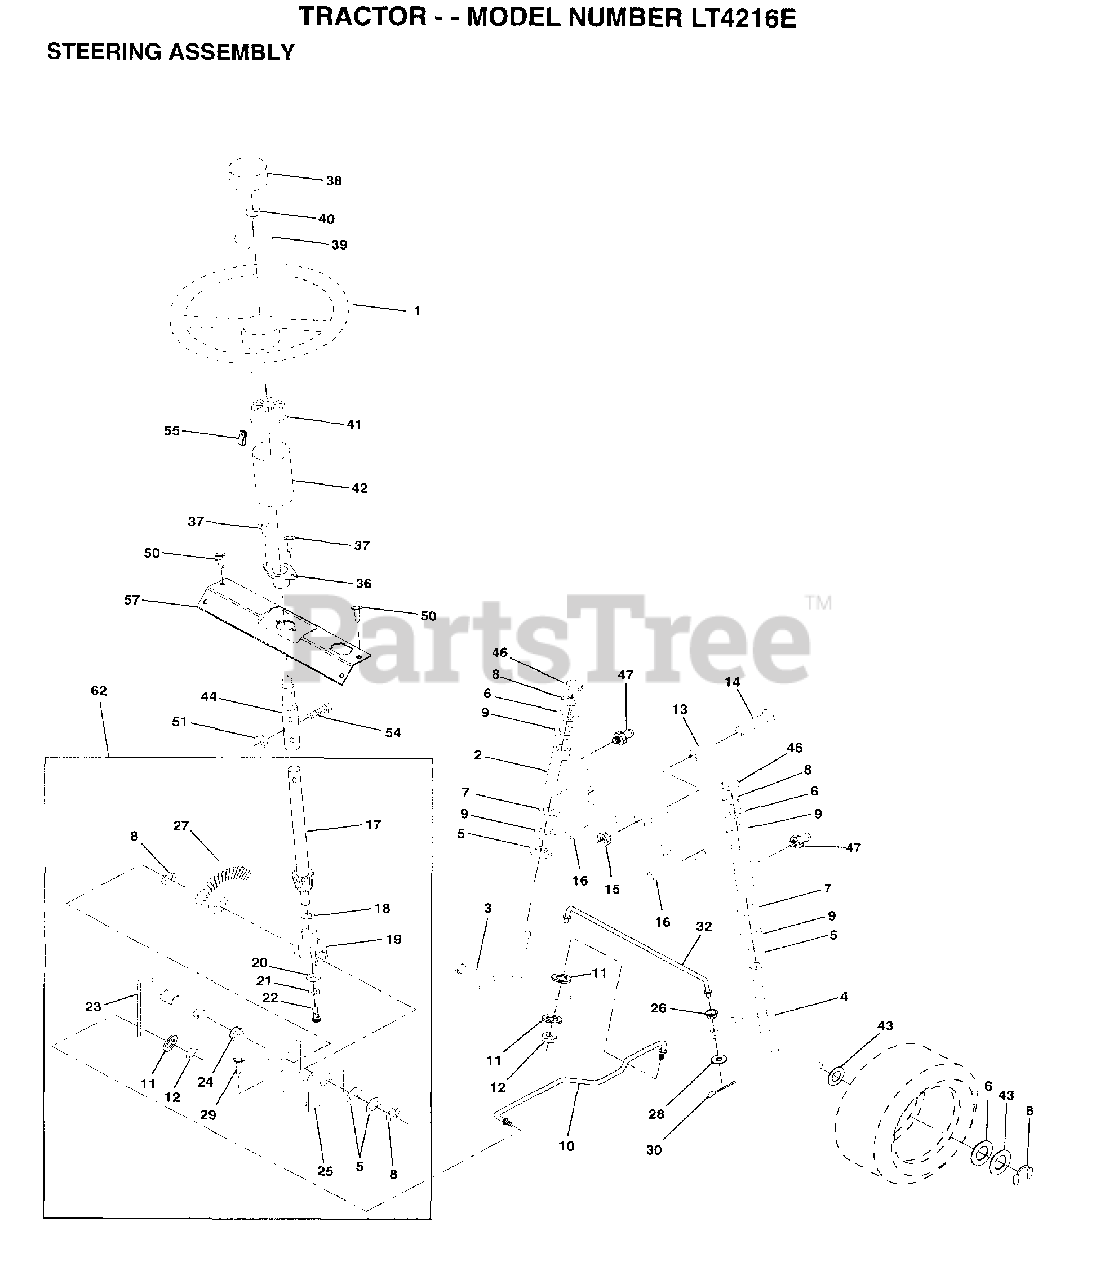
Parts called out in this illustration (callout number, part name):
1	WHEEL STR AYP BLK
2	AXLE ASM FRONT
3	SPINDLE LH
4	SPINDLE RH
5	WASHER .T
6	WASHER
7	WASHER
8	RING
9	COL. SRTG. BEAR.
11	LOCKWASHER
13	BEARING
14	BOLT HEX 5/8-11
15	"NUT-LOC,FLANGE LT"
16	AXLE PIN
17	SHAFT ASM STEERIN
18	THRUST WASHER
19	SUPPORT.SHAFT
21	LOCKWASHER
22	SCREW.SCKTHD.CAP
24	NYLINER T
25	"BRKT,STEERING"
26	BUSHING.DRAGLINK
27	GEAR SECTOR
28	WASHER
29	SCREW
30	COTTER PIN
32	TIE ROD
38	CAP STEER AYP
39	WASHER T
40	GRIPCO NUT
41	ADAPTER-WHEEL LT
42	BOOT SHAFT STEER
43	WASHER
46	CAP
47	ZERK M
50	SCREW HEX CRT
51	NUT LK HEX W/INS 5/16-18 UNC P
54	BOLT
55	CLIP TINNERMAN
57	SUPPORT SHAFT STR
